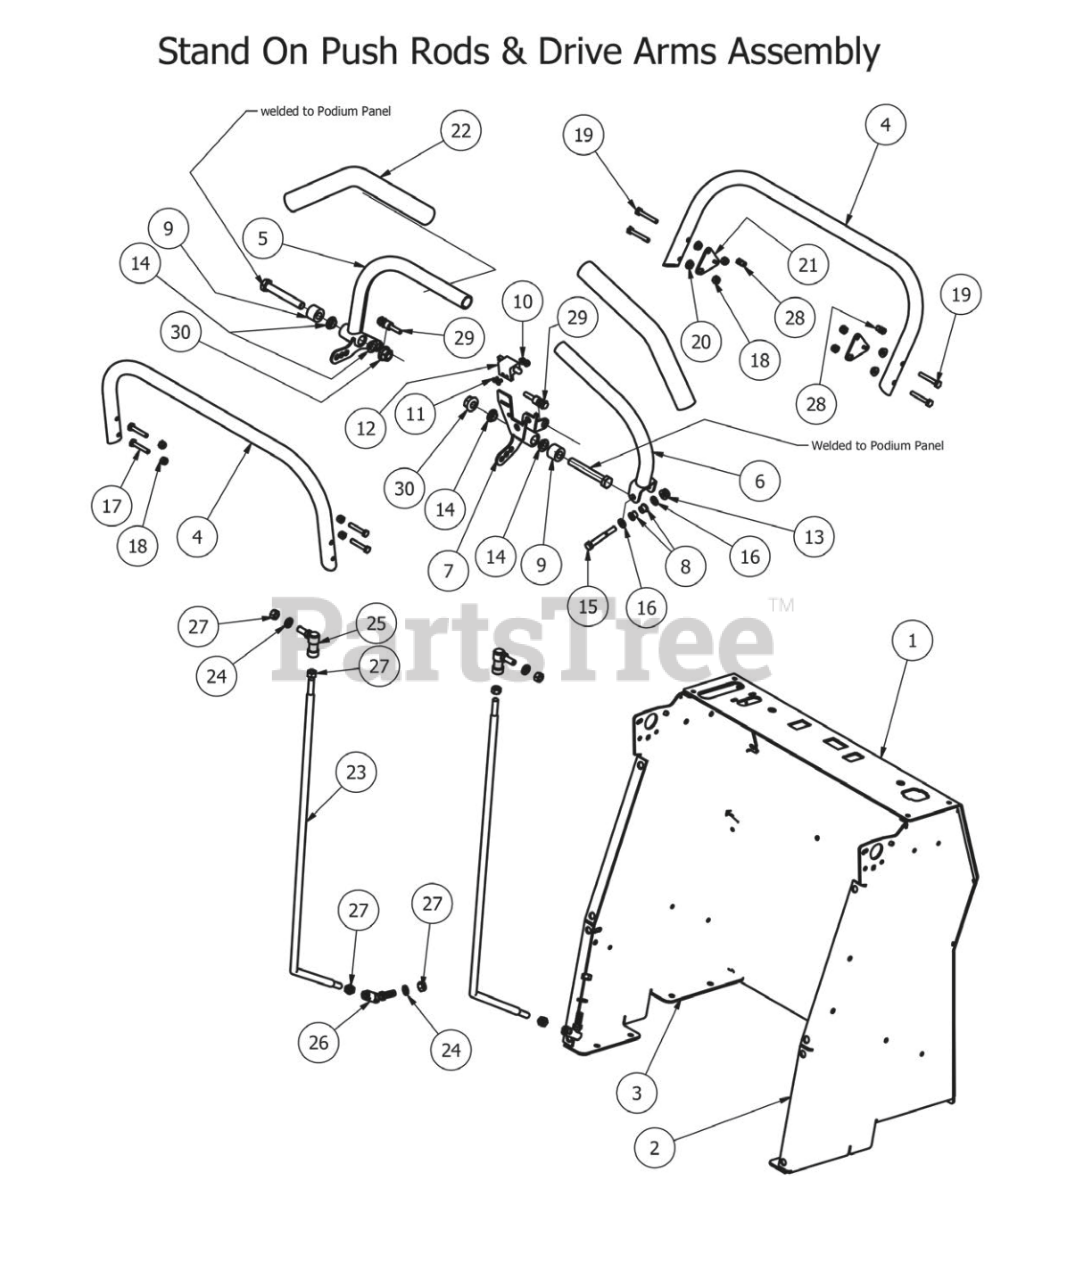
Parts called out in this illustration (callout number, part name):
1	Podium Front Panel
2	Podium Panel Right Side
3	Podium Panel Left Side
4	Support Handle Stand Up (Front & Back)
5	Left Steering Handle Assembly
6	Right Steering Handle Assembly
7	Safety Kill Switch Assembly Bracket
8	Stand On Flange Bushing-Steering Arms
9	Steering Arm Spacer-Stand On
10	10-24 Nylon Insert Locknut
11	1024 X 5/8" Buttonhead Bolt
12	Safety Switch
13	5/16-18 Nylon Flange Nut
14	Bushing for 2012 Drive Arms
15	5/16" x 2 1/2" Bolt
16	1/4" Flat Washer
17	1/4-20 x 1 1/2" Bolt
18	1/4" Nylock Nut
19	1/4-20x 1-3/4" Hex Bolt
20	1/4-20 Hex Flange Nuts Zinc w/Serrations
21	Neutral Safety Tab
22	Black Steering Grip
23	Push Rod Stand On
24	3/8" Lock Washer
25	3/8-24 Quick Release Ball Joint
26	3/8-24 Ball Joint
27	3/8" Fine Threaded Jam Nut
28	Magnet-Steering Arm-Stand On
29	Safety Switch Harness
30	1/2-13 Hex Flange (GR.G) ZC
